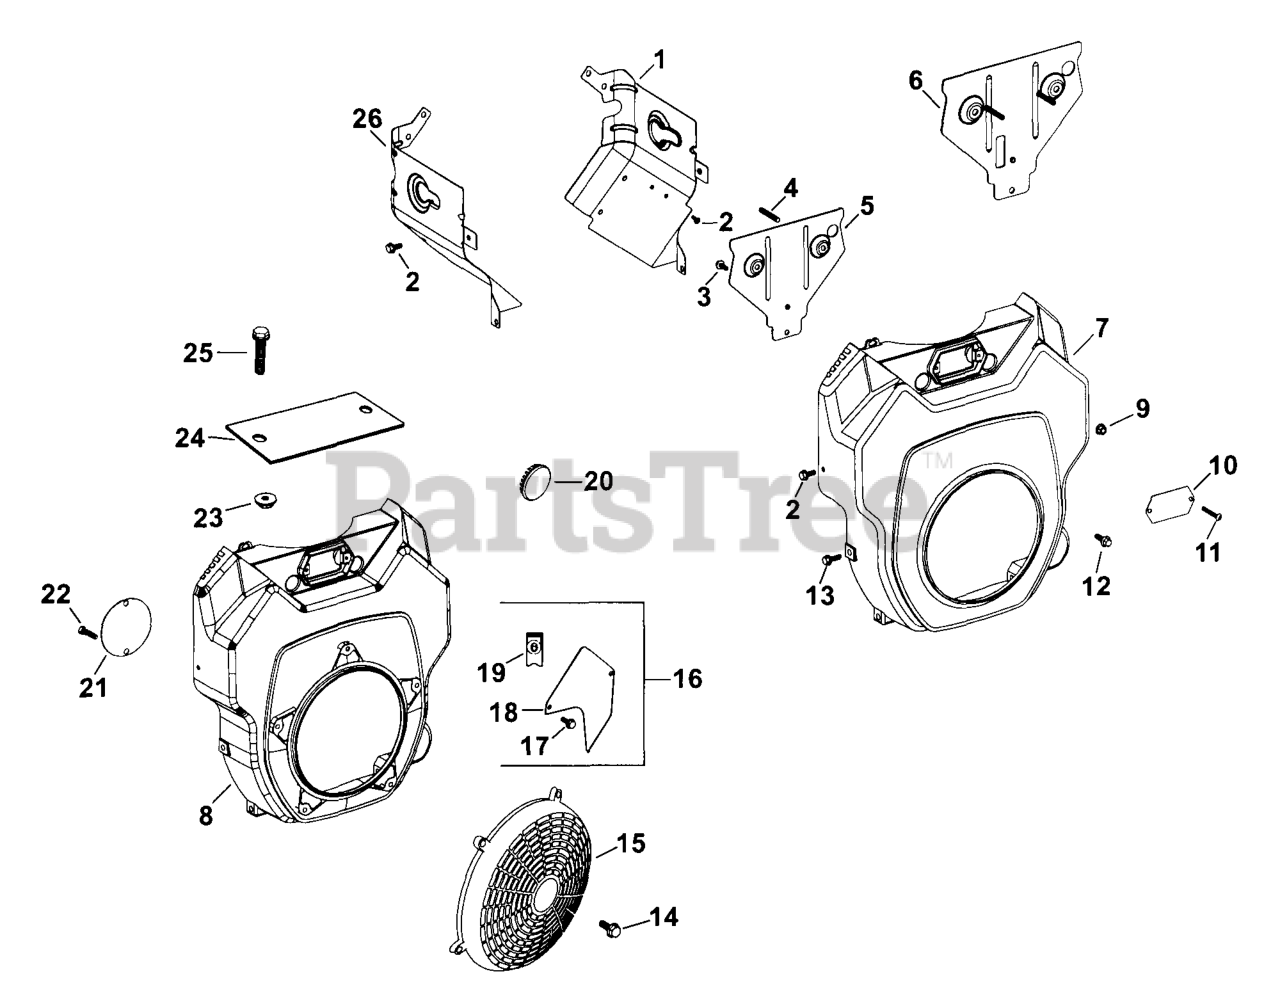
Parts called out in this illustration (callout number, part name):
1	BAFFLE, NO. 1 CYLINDER - DISCONTINUED
2	SCREW,FLG THD FRM M6X1.0X16-(#25086397S)
3	SCREW,FLG THD FRM M5X0.8X16-(#25086398S)
5	BAFFLE, VALLEY
8	Housing, blower
12	SCREW, FLNGTHDFRM M6X1.0X30-(#25086401S)
13	SCREW,FLG THD FRM M6X1.0X20-(#25086396S)
26	BAFFLE, NO. 2 CYLINDER - (#DSC)
